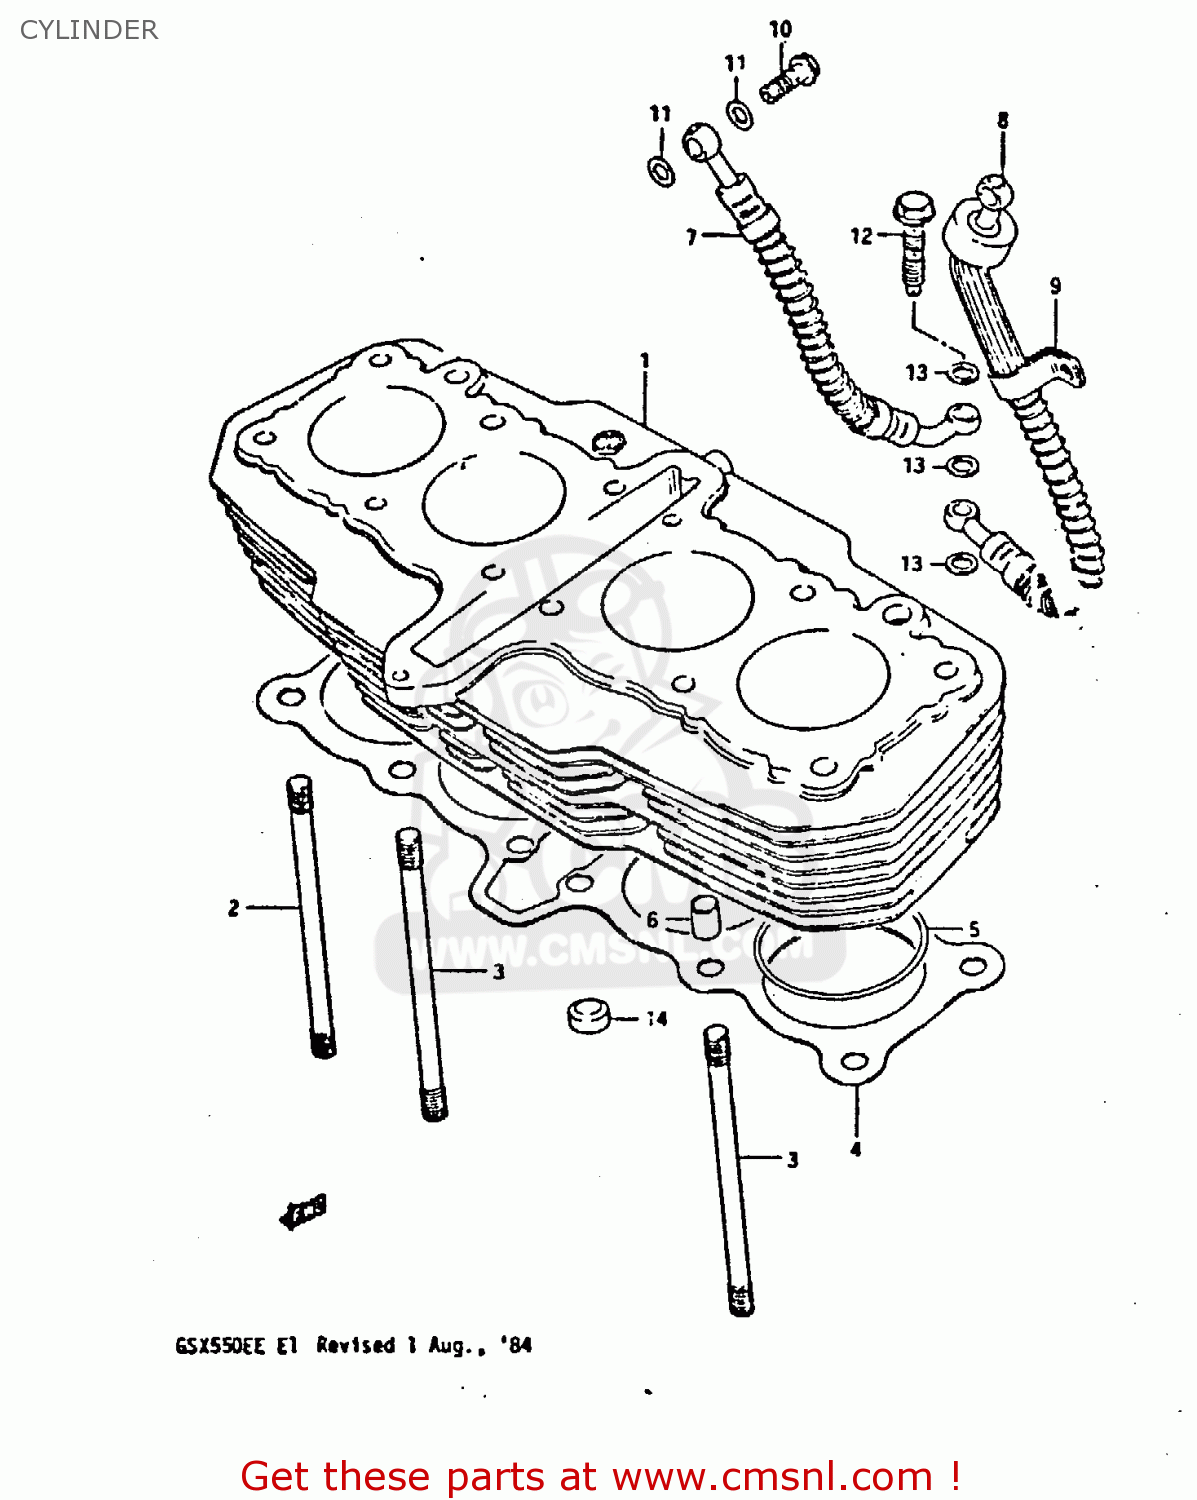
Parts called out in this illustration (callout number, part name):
1	CYLINDER
2	STUD
3	STUD
4	GASKET,CYLINDER (MCA)
5	O RING(D:2,ID:61)
6	PIN
7	HOSE,OIL CRANKCASE,R
8	HOSE,OIL CRANKCASE,L
9	CLAMP,OIL HOSE CRANKCASE
10	BOLT UNION
11	GASKET 8.2X14X1 (NAS)
12	BOLT,OIL PIPE
13	WASHER(10X15X1.5)
14	PAD,CYLINDER HEAD
